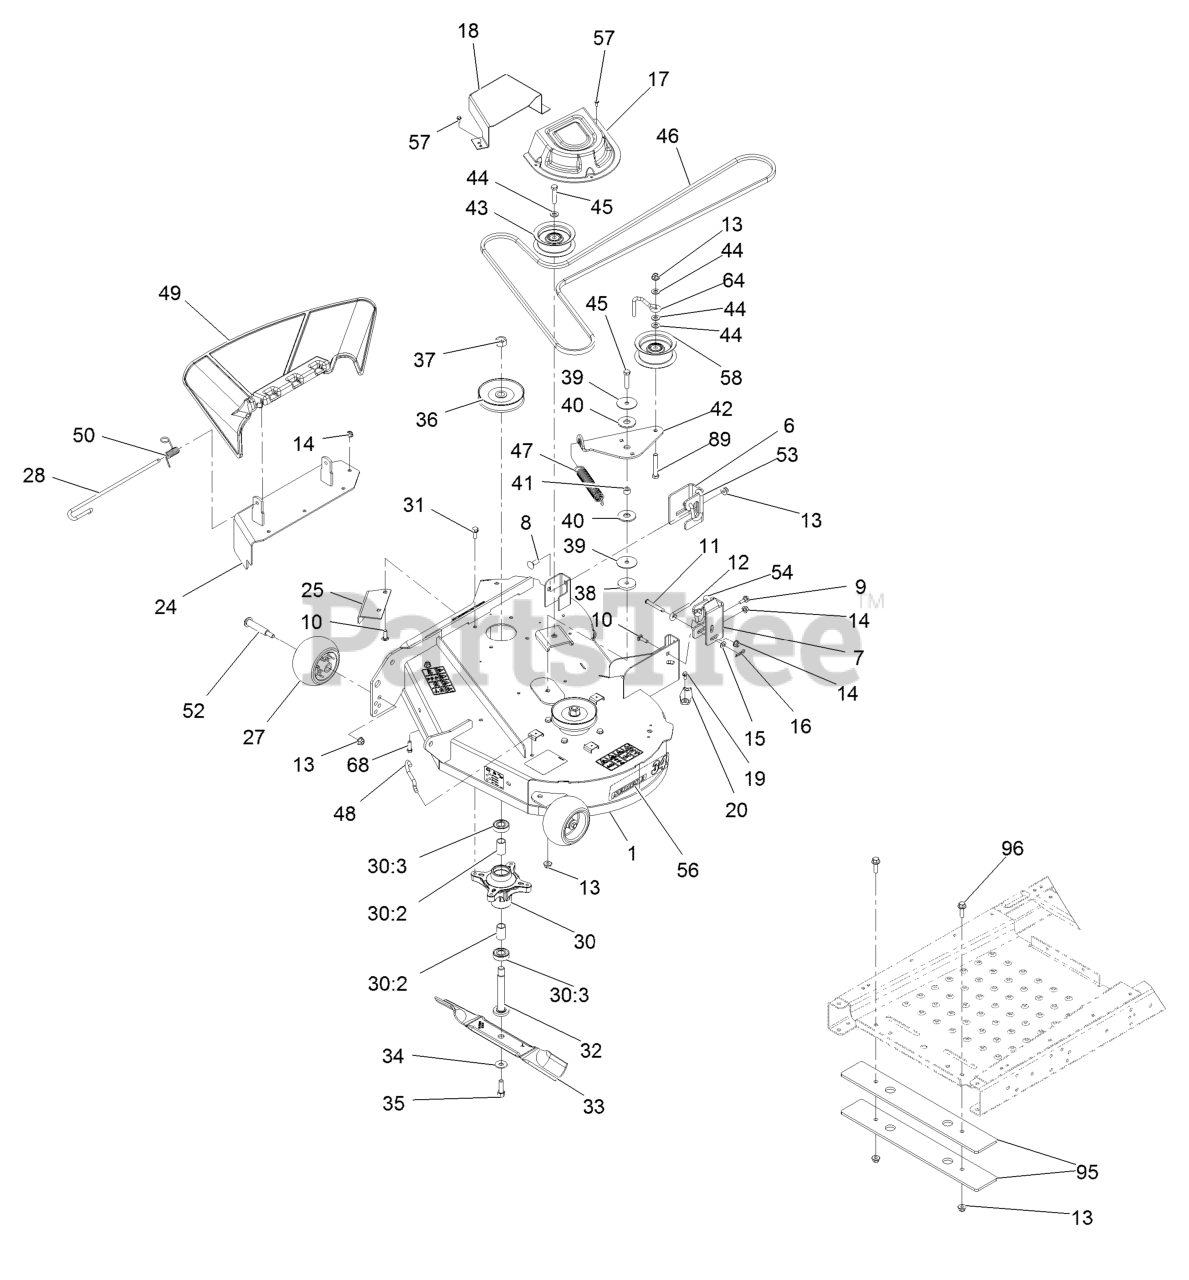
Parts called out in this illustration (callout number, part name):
1	Deck-34 W/Decals
6	Bracket-Hanger, RH
7	Bracket-Hanger, LH
8	Bolt-Carriage 3/8-16 X 1
9	Screw-HH Flg 1/4-20 X 3/4 Tf
10	Bolt-Carriage 5/16-18 X 1 Sp
11	Pin-Clevis
12	Rod-Level, Deck
13	Nut-Nyloc 3/8-16 Flg
14	Nut-Nyloc 5/16-18 Flg
15	Washer-5/16 SAE
16	Hairpin-Cotter
17	Cover-Belt
18	Cover-Deck Belt
19	Screw-HWH 1/4-20 X 1/2 Taptite
20	Cover-Washout Port
24	Cover-Discharge W/Decal
25	Baffle-Cutoff
27	Roller-Scalp, Anti
28	Pin-Chute
30	Spindle ASM
30:3	Bearing-Ball
31	Screw-HWH 3/8-16 X 7/8 Taptite
32	Shaft-Spindle
33	Blade-Hi Lift
34	Washer-Spring Disc
35	Screw-HH 7/16-20 X 1.36 Gr8
36	Pulley ASM
37	Nut-Hex 5/8-18
38	Washer-Plain
40	Washer-Friction, Composite
42	Arm-Idler
43	Pulley-Idler, Flat
44	Washer-3/8 SAE
45	Screw-HH 3/8-16 X 1 3/4
46	Belt-V
47	Spring-Extension
48	Hook-Return, Spring
49	Deflector-Discharge
50	Spring-Torsion
52	Bolt-HH Shoulder 3/8-16 X 3.79
53	Link-Retention, Deck (RH)
54	Link-Retention, Deck (LH)
56	Decal - Series 2 34
57	Screw-HWH #10-24 X 1/2 Taptite
58	Pulley-Idler,Flat
64	Guide-Idler, Belt
68	Screw-HH 5/16-18 X 5/8
89	Screw-HH 3/8-16 X 2 1/2
95	Plate-Weight
96	Screw-HHF
